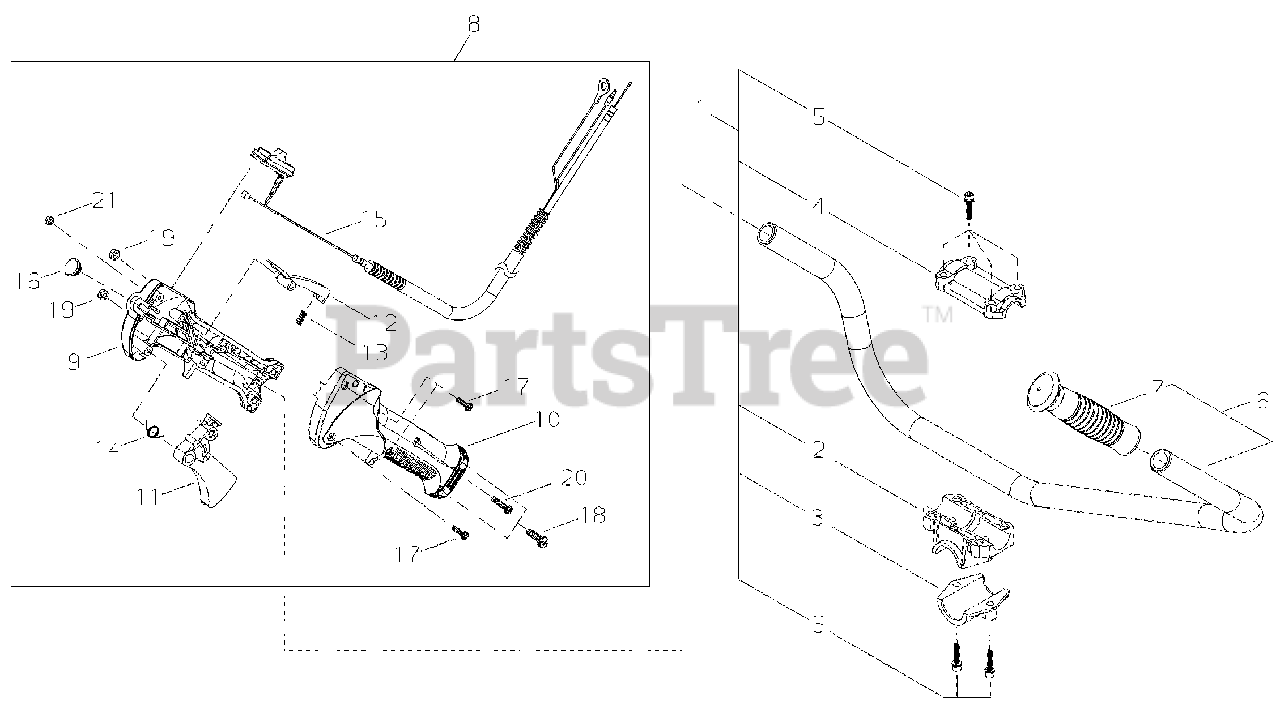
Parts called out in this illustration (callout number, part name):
1	HANDLE BRACKET KIT
2	BRACKET, HANDLE - LOWER
3	BRACKET, MOUNTING
4	BRACKET, HANDLE - UPPER
5	SCREW - 5X25
6	HANDLE ASSY
7	GRIP - LEFT
8	THROTTLE LEVER ASSY
9	HANDLE, CONTROL - RIGHT
10	HANDLE, CONTROL - LEFT
11	TRIGGER, THROTTLE
12	LEVER, TRIGGER LOCKOUT
13	SPRING
14	SPRING
15	THROTTLE CONTROL ASSY
16	PLUG
17	SCREW - 4X16 -- TAPPING
18	SCREW - 5X20
19	NUT - 5
20	SCREW - 4X23
21	NUT - 4
